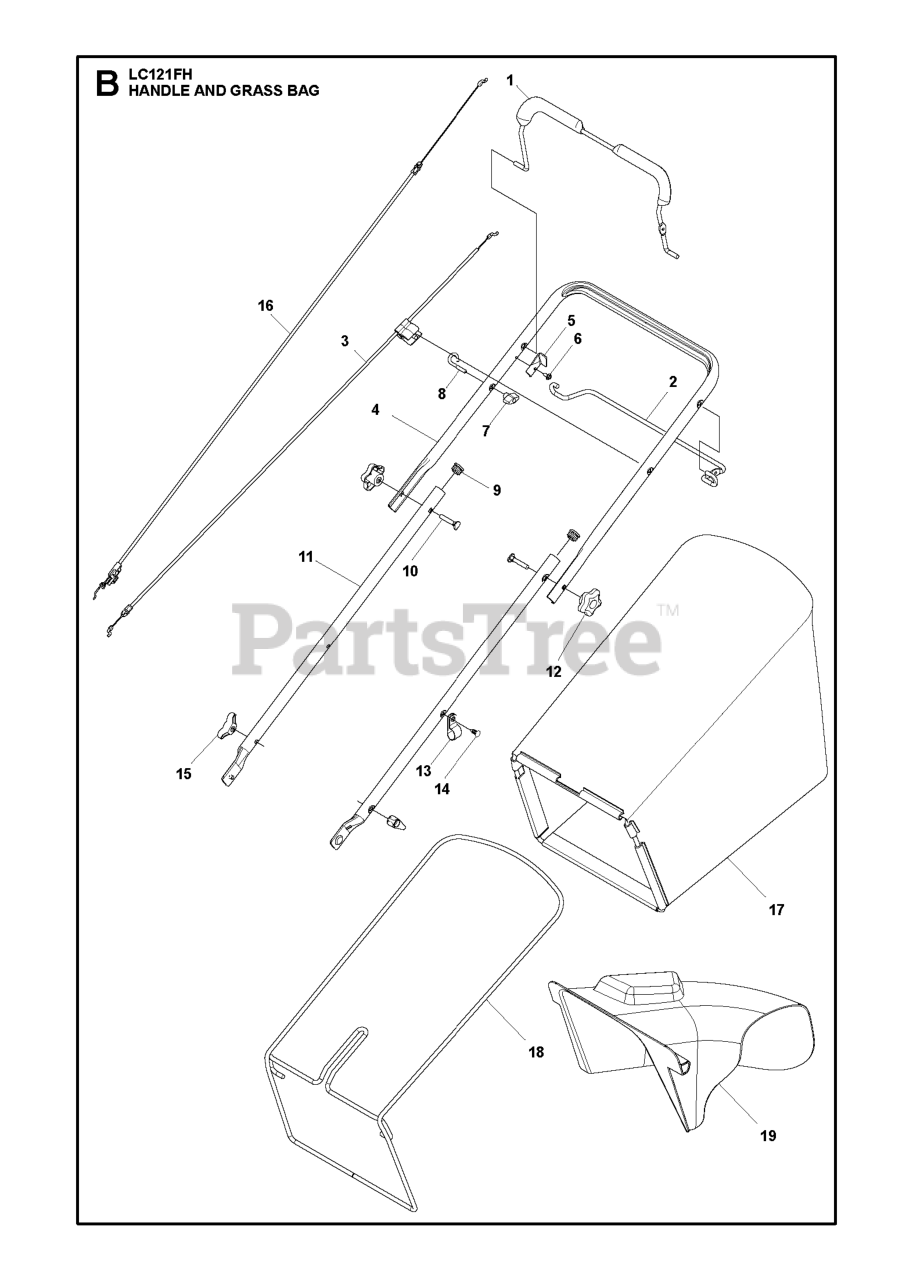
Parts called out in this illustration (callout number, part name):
1	BAIL.ARM.ASSY:STRAIGHT OM
2	BAIL.CONT.DR.S/S.ROUND.BLACK
3	RP.CABLE.MZR.RGD.PLUS.STRT
4	HANDLE.UPP.DST.EXTCR.SM.SP.498
5	BRACKET.UPSTOP.RT
6	SCREW
7	T-KNOB.NEW ROPE GUIDE
8	GUIDE.ROPE.BLK.ZINC.CHROM
9	PLUG.PLASTIC.7/8".14-20.GAUGE
10	BOLT.CONCAVE.HEAD.RETAINING
11	HANDLE.LOW.2PC.2POS.21EFF.498
12	KNOB.HANDLE.PLASTIC.STAR.BLACK
13	CLIP.CABLE.BLK
14	FASTENER.PUSH.O.250X0.783
15	KNOB, DEFLECTOR
16	CABLE.DRIVE.21 EFF.FGD
17	GBAG.C361029ER.HUSQ.GRY.21EFF
18	FRAME.GBAG.AWD.21.BLACK
19	CHUTE.DISCHARGE.21EFF.HW
